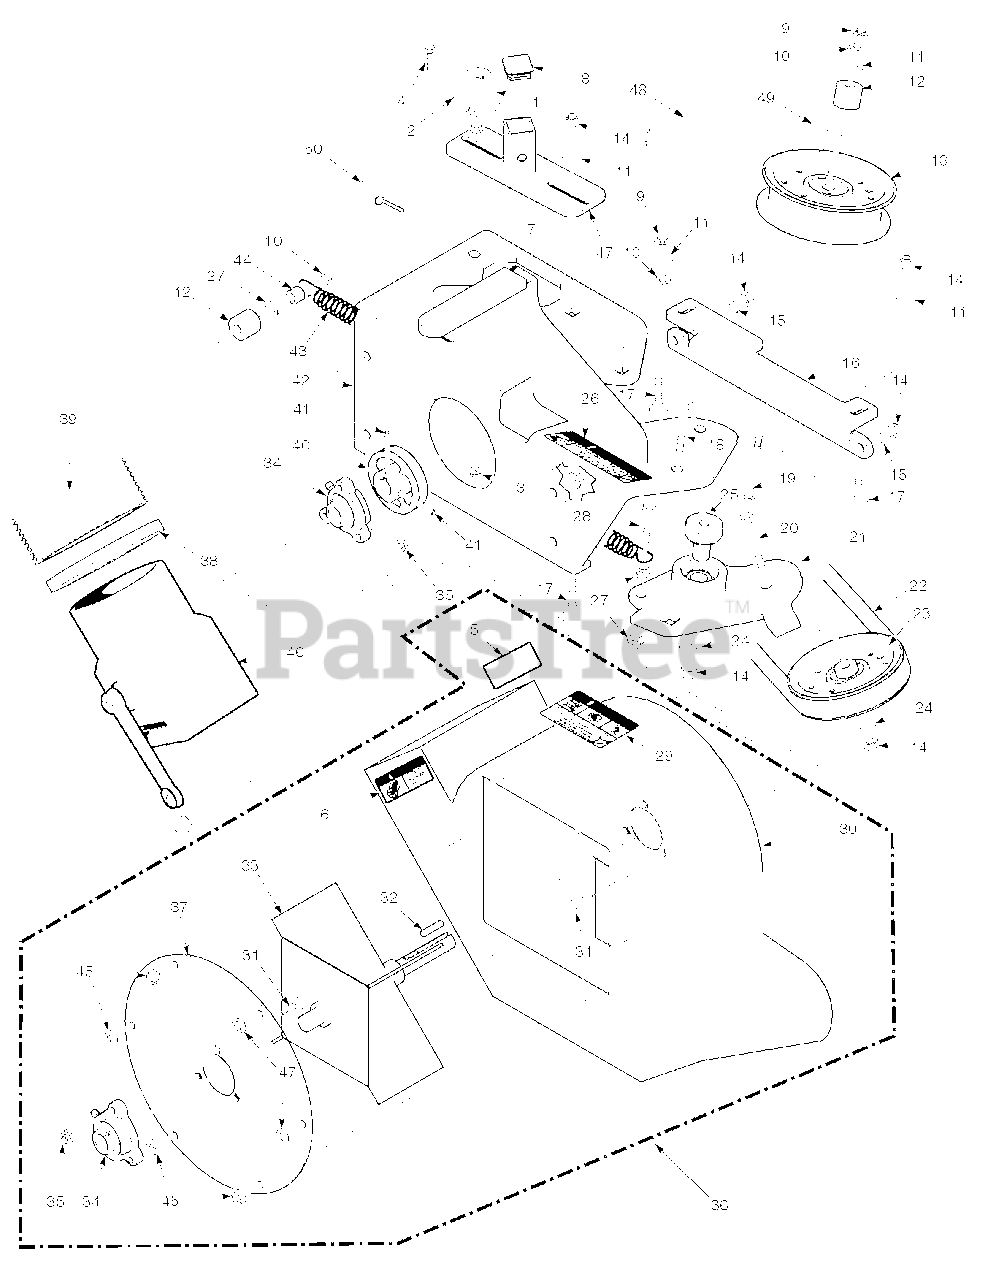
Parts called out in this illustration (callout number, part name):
1	Pin, Ring 2-1/4" Long
2	Lanyard, Deck Height Pin
3	Nut, Serr. Flange 1/4-20
4	Bolt, Hex Head 1/4-20 x 1-1/4"
5	Decal, Blower
6	Decal, Rotating Blower
7	Grip, Blower Lever
8	Cap, Square
9	Nut, Push On 3/8 Thread
10	Lock Nut, 3/8-16
11	Flatwasher, 3/8-.391 x .938 x .105
12	Spacer
13	Pulley, Idler 4" Dia.
14	Nut, Elastic Stop 3/8-16
15	Lockwasher, 3/8-16
16	Plate, Catcher Mounting
17	Bolt, Carr. 3/8-16 x 1-1/2"
18	Bolt, Hex Head 3/8-16 x 3" - 52"
19	Bolt, Hex Head 3/8-16 x 3-1/2"
20	Bolt, Hex Head 3/8-16 x 1-3/4"
21	Idler Arm Assembly
22	Belt, GC-STT-61V
23	Pulley, 3-1/2" O.D., GC-STC
24	Washer, 3/8 Hardened
25	Pivot, Idler
26	Decal, Belt Cover
27	Nut, Serr. Flange 3/8-16
28	Bolt, Hex Head 3/8-16 x 1-1/2 Gr. 8
29	Decal, Danger
30	Blower Housing Weldment
31	Bolt, Carr. 5/16-18 x 3/4" Gr. 5
32	Key, 1/4 x 1/4 x 1-1/2"
33	Fan Weldment
34	Bearing Assembly
35	Nut, Elastic Stop 5/16-18
36	Blower Housing Assembly, GC-STT
37	Cover, Blower Housing
38	Clamp, 8-5/8" Max Dia.
39	Hose, 8.00" Dia. x 68" Long
40	Pulley, 4-3/4" O.D. - 1" Bore
41	Set Screw, 5/16-18 x 3/8"
42	Frame, Blower Mount
43	Spring, Main Drive
44	Spacer
45	Nut, Serr. Flange 5/16-18
46	Adapter w/Strap
47	Receiver Weldment, Mounting Post
48	Hair Pin Cotter, .177 x 3-1/4"
49	Dust Shield
50	Quick Pin, 5/16" Dia.
